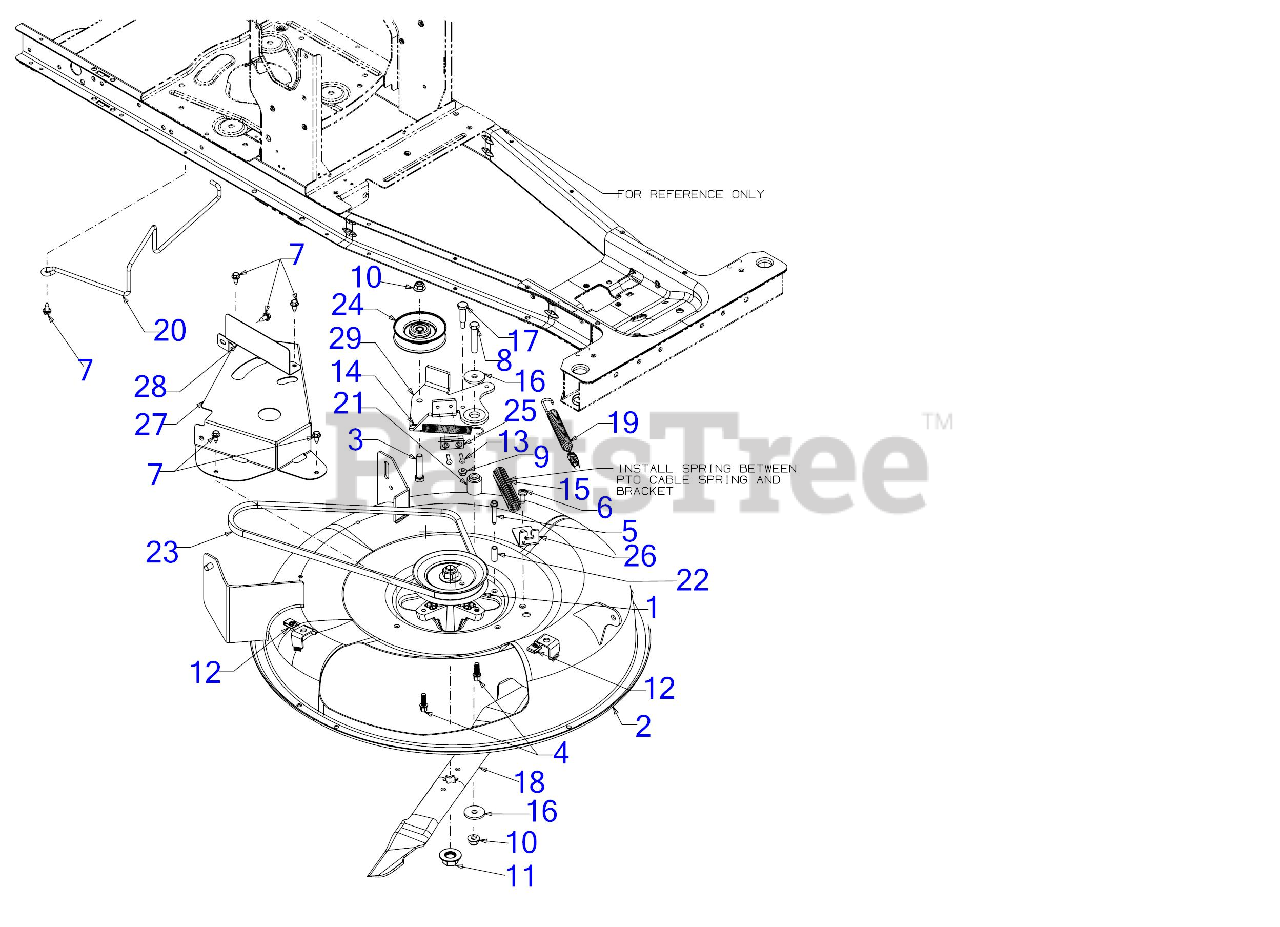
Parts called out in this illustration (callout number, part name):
1	SPINDLE ASSEMBLY
3	HEX SCREW 3/8-16 x 1.75 GR5
4	SCREW 5/16-18 X .875
5	SCREW 1/4-20 x 1.50"
6	SCREW 5/16-18 x .750
7	SCREW 1/4-20X.625
8	SCREW 3/8-16 x 2.0 GR5
9	FLANGE LOCK NUT
11	HEX NUT
12	U-NUT
13	POP RIVET
14	EXTENSION SPRING
15	SPRING
16	WASHER
17	SHOULDER SCREW
18	24" BLADE (3N1)
19	PTO CABLE
20	DECK BELT KEEPER
21	SHOULDER SPACER 18MM x 5.2MM
22	SPACER
23	V-BELT A x 43.5
24	PULLEY-3.54" DIA
25	SPINDLE BRAKE PAD
27	SPINDLE COVER 24"
28	DECK SHIELD (LH)
29	IDLER BRACKET DECK
